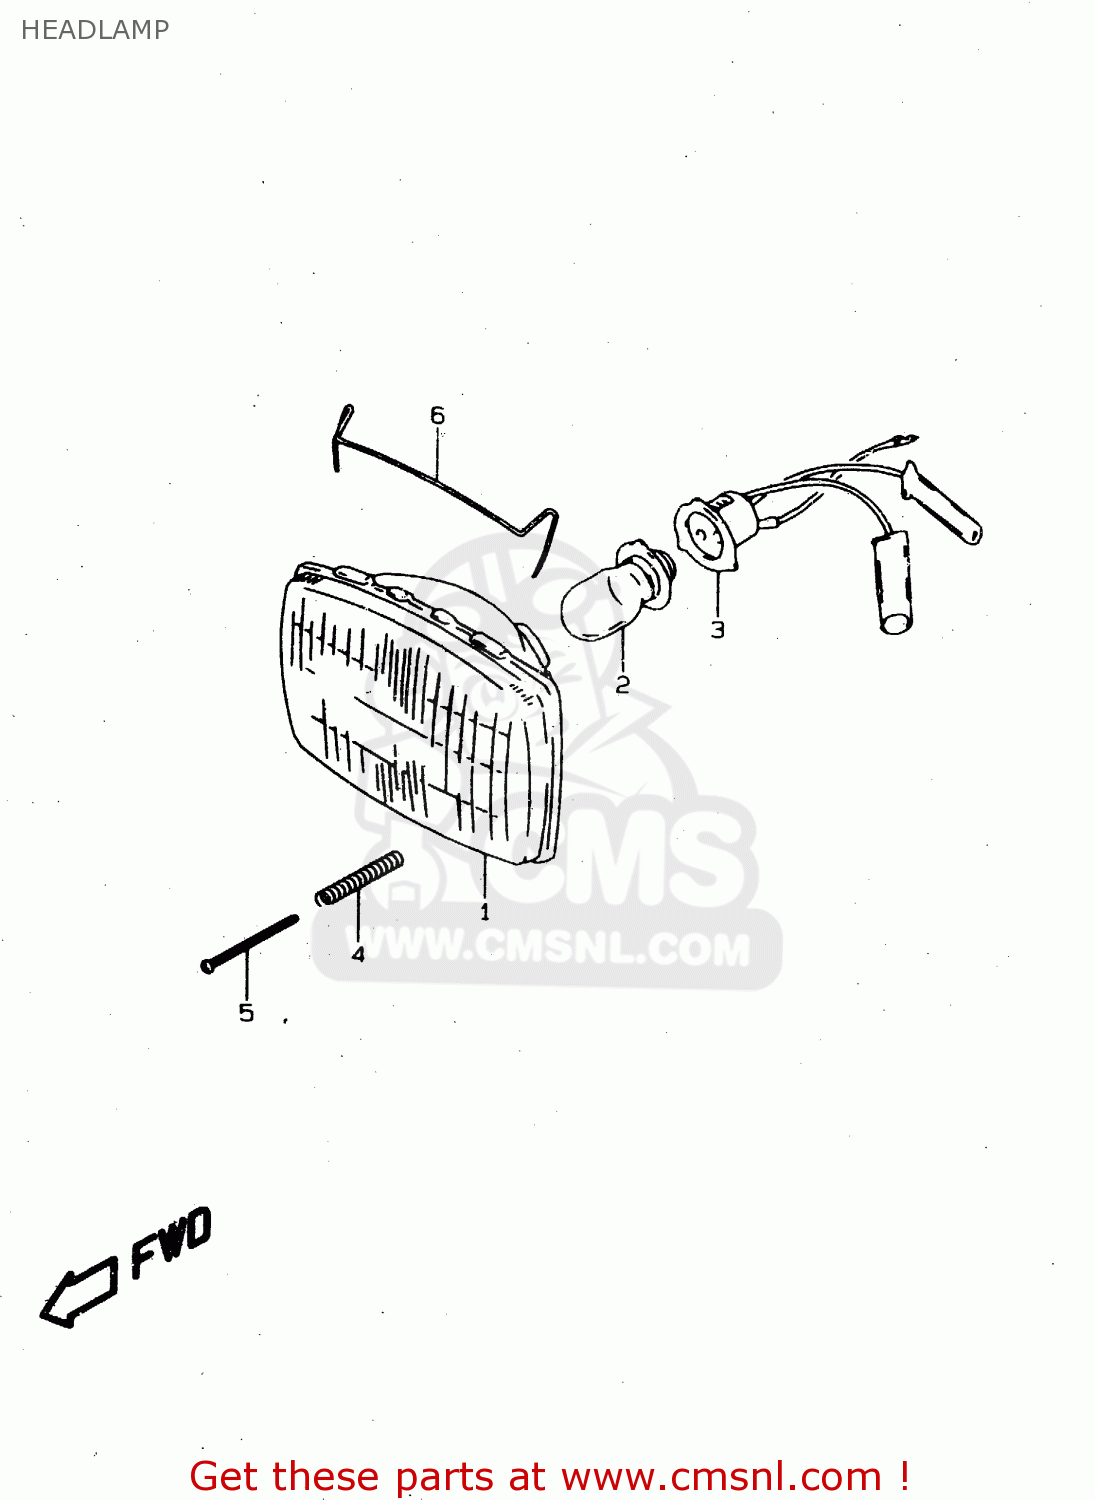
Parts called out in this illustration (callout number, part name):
1	LAMP UNIT
2	BULB(6V15/15W/STANLEY,A3598HA)
3	SOCKET,HEADLAMP
4	SPRING,HEAD LAMP ADJUSTER
5	SCREW
6	SPRING,SUPPORT
